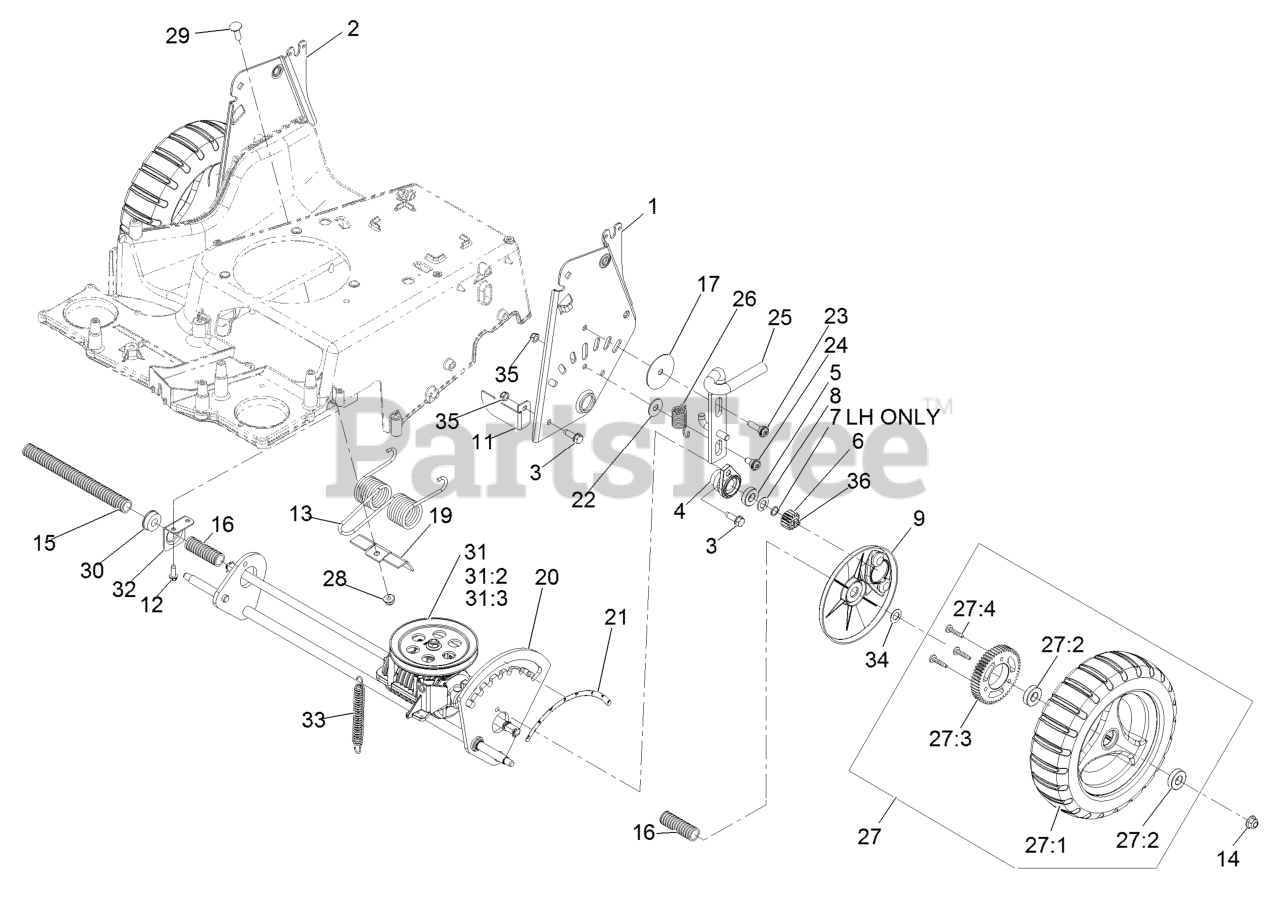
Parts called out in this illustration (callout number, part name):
1	LH HOC PLATE ASM
2	RH HOC PLATE ASM
3	SCREW-THD ROLL, HWH
4	RETAINER-BEARING
5	BEARING-BALL
6	GEAR-PINION, 15T
7	RING-RETAINING
8	WASHER-THRUST
9	COVER-GEAR
12	SCREW-HWHTF
13	SPRING-TORSION
14	NUT-HF, NI
15	CONDUIT-CONVOLUTED
16	CONDUIT-CONVOLUTED
17	WASHER-PLAIN
19	BRACKET
20	AXLE-REAR
21	DECAL-HOC, REAR
23	SCREW-SHOULDER, BHTF
24	BOLT-SHOULDER
25	LOCK-HEIGHT, ADJUST
26	SPRING-EXTENSION
27:2	BEARING-BALL
27:4	SCREW-DRIVE
28	NUT-HF, NI
29	BOLT-CARR
30	BEARING-BALL
31	TRANSMISSION KIT
31:2	PIN-SNAP
31:3	RING-RETAINING
33	SPRING-EXTENSION
34	WASHER-PLAIN
35	NUT-LOCK, NI
36	PIN-SNAP
